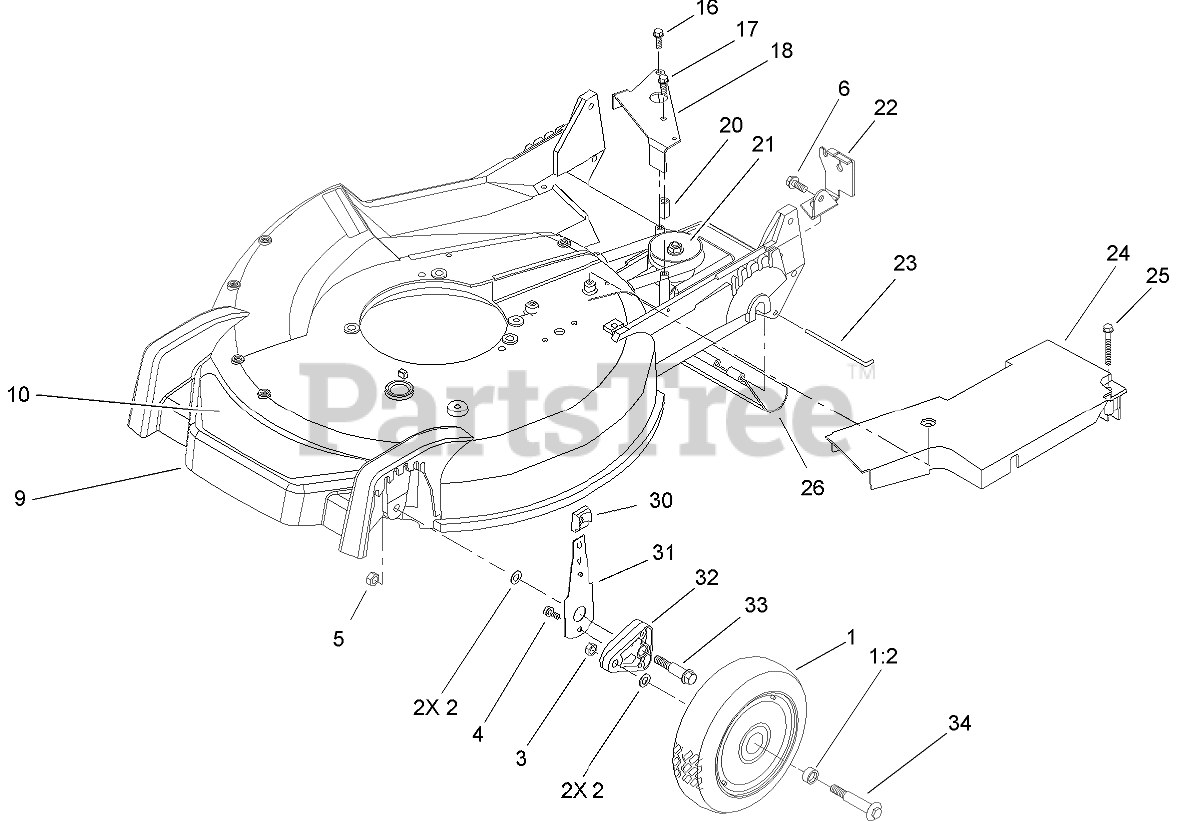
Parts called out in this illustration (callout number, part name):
1	WHEEL ASM
1:2	BUSHING
2	WASHER
4	SCREW-HWH
5	NUT-LOCK
6	SCREW-HWHTF
9	HOUSING ASM
10	DECAL-HOUSING
16	SCREW-HWH
17	SCREW-HWHTF
18	BRACKET-TRANSMISSION ACTUATOR
20	BUSHING-PLATE, ACTUATOR
21	GEAR CASE ASM
22	BRACKET-CABLE, TRACTION
23	ROD-SHIELD
24	COVER-BELT
25	SCREW-HHFTF
26	SHIELD-TRAILING
30	KNOB-ARM
31	FRONT SPRING ARM ASM
32	ARM-PIVOT, FRONT
33	BOLT-SHOULDER
34	BOLT-SHOULDER
